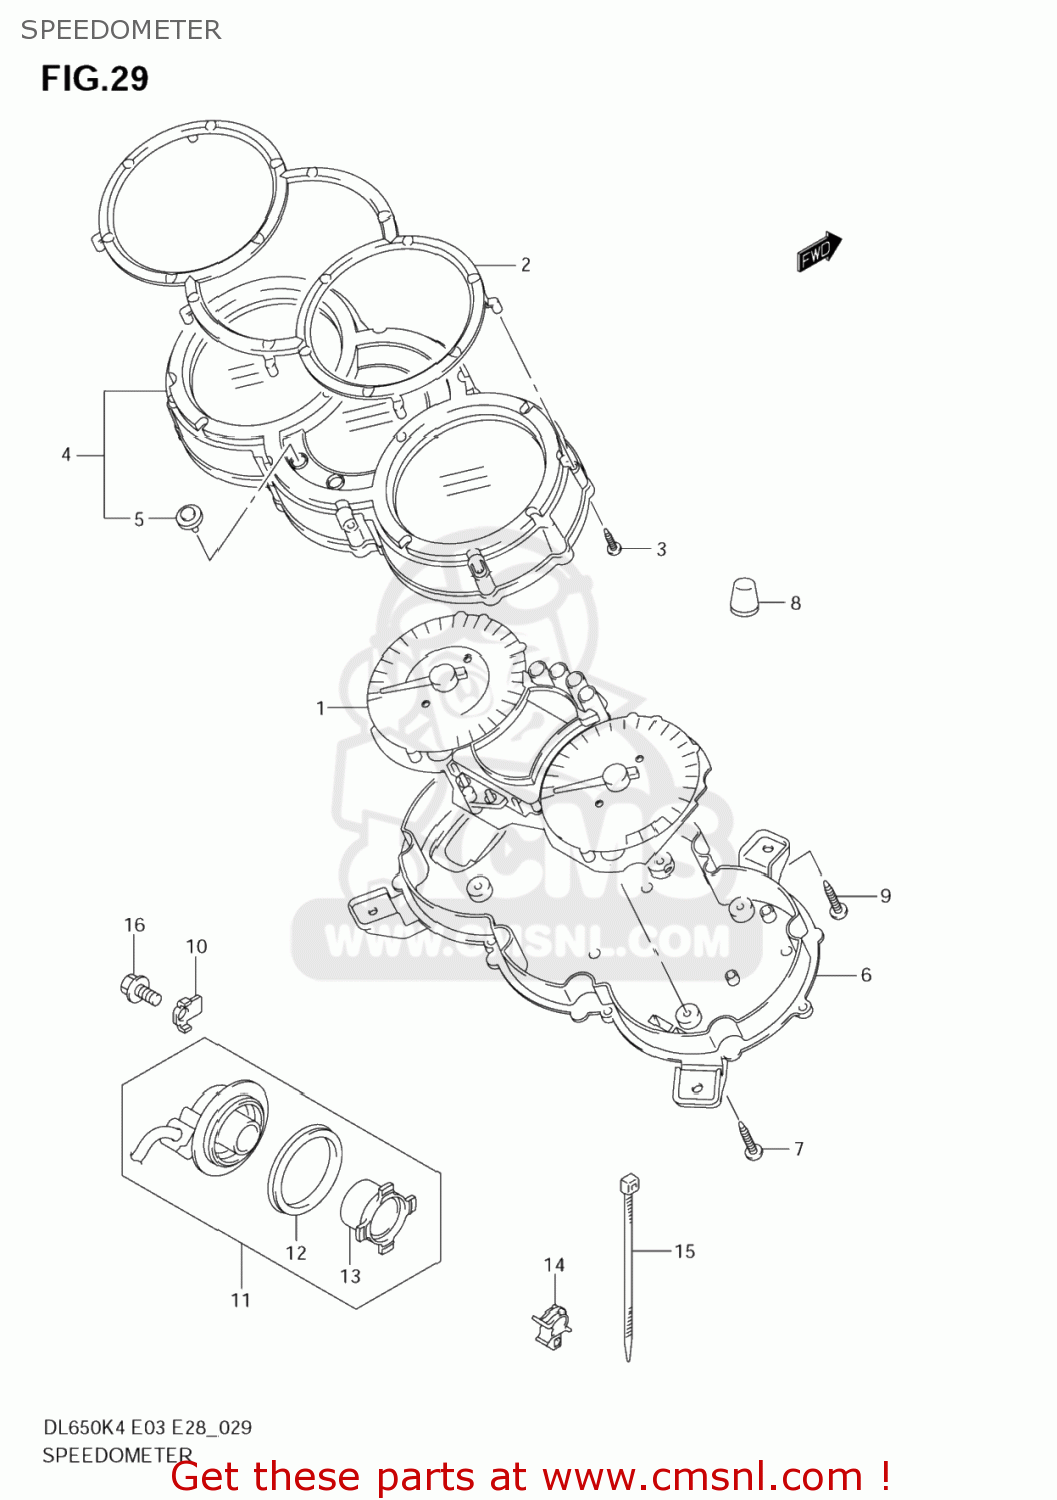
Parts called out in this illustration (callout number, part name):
1	SPEEDOMETER
2	COVER
3	SCREW(2.3X8)
4	CASE,UPR
5	SWITCH,LEVER
6	CASE,LWR
7	SCREW(3X16)
8	CUSHION,SPEEDOMETER
9	SCREW
10	GUIDE,SENSOR LEAD
11	SENSOR COMP,SPEED
12	SEAL,OIL(44X55X6)
13	MAGNETO
14	CLAMP
15	CLAMP(L:100)
16	BOLT
